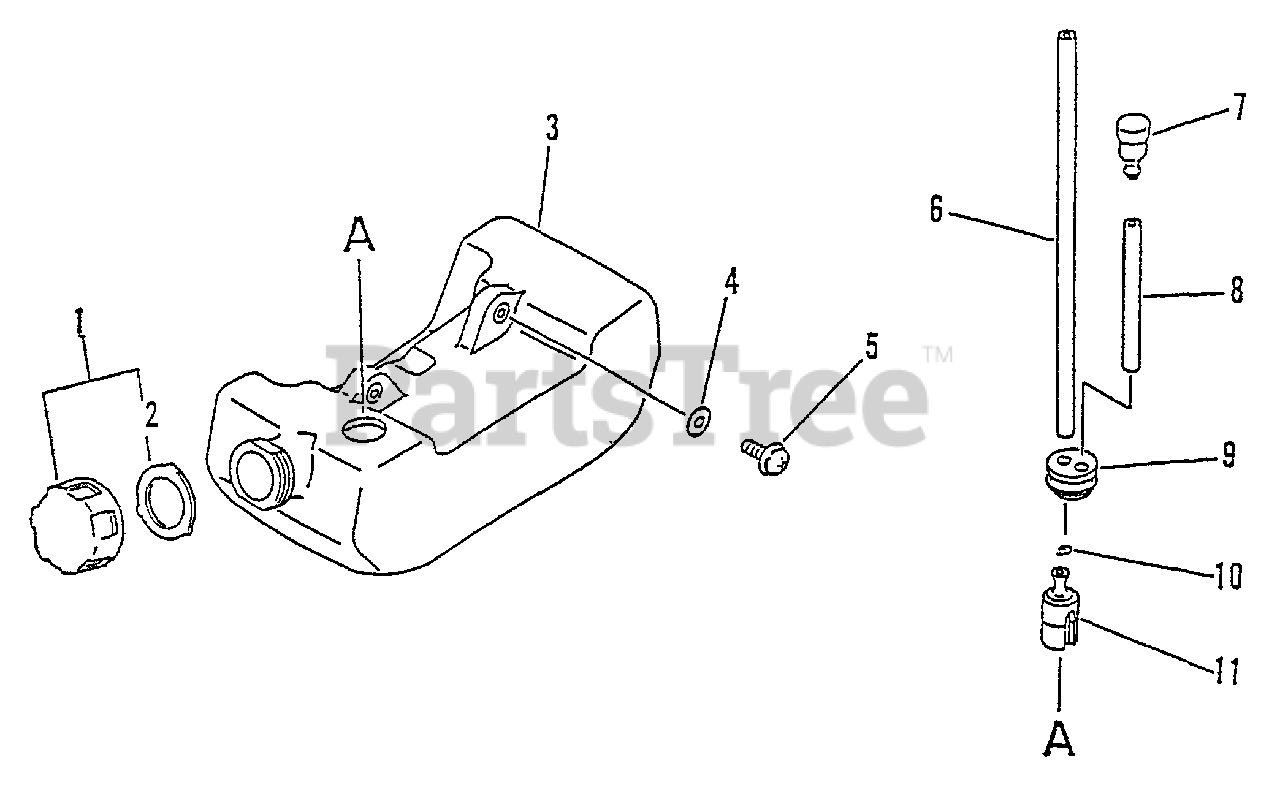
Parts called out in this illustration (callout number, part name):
1	CAP ASSY
2	GASKET, FUEL CAP
3	TANK, FUEL
4	WASHER 5.5×12×0.8
5	SCREW 5×16
6	PIPE, FUEL 3x-5x-180
7	VENT ASSY
8	PIPE, FUEL 3x-5x-70 BLACK
9	GROMMET, FUEL
10	CLIP 6 MM
11	FILTER, FUEL
